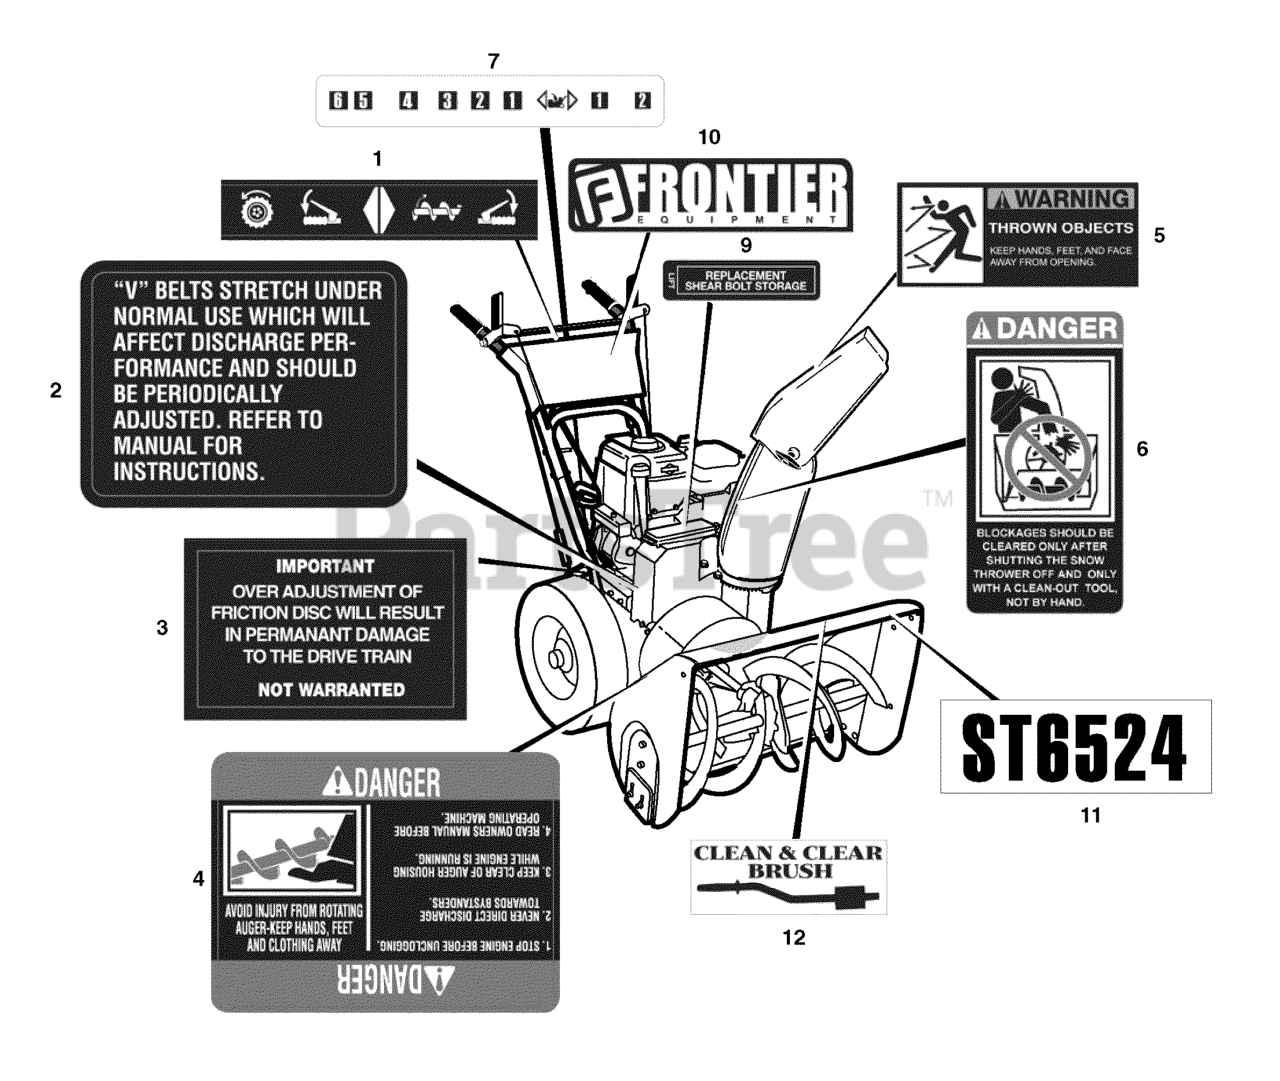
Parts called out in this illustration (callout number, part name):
1	DECAL, Hand Control
2	DECAL, V-Belts
3	DECAL, Over Adjustment
4	DECAL, Rotating Auger
5	DECAL, Thrown Objects
6	DECAL, Unclogging Chute
7	DECAL, Speed Control
9	DECAL, Shear Bolts
10	LOGO NAMEPLATE, Frontier
11	DECAL, ST6524
12	DECAL, Clean & Clear Brush
